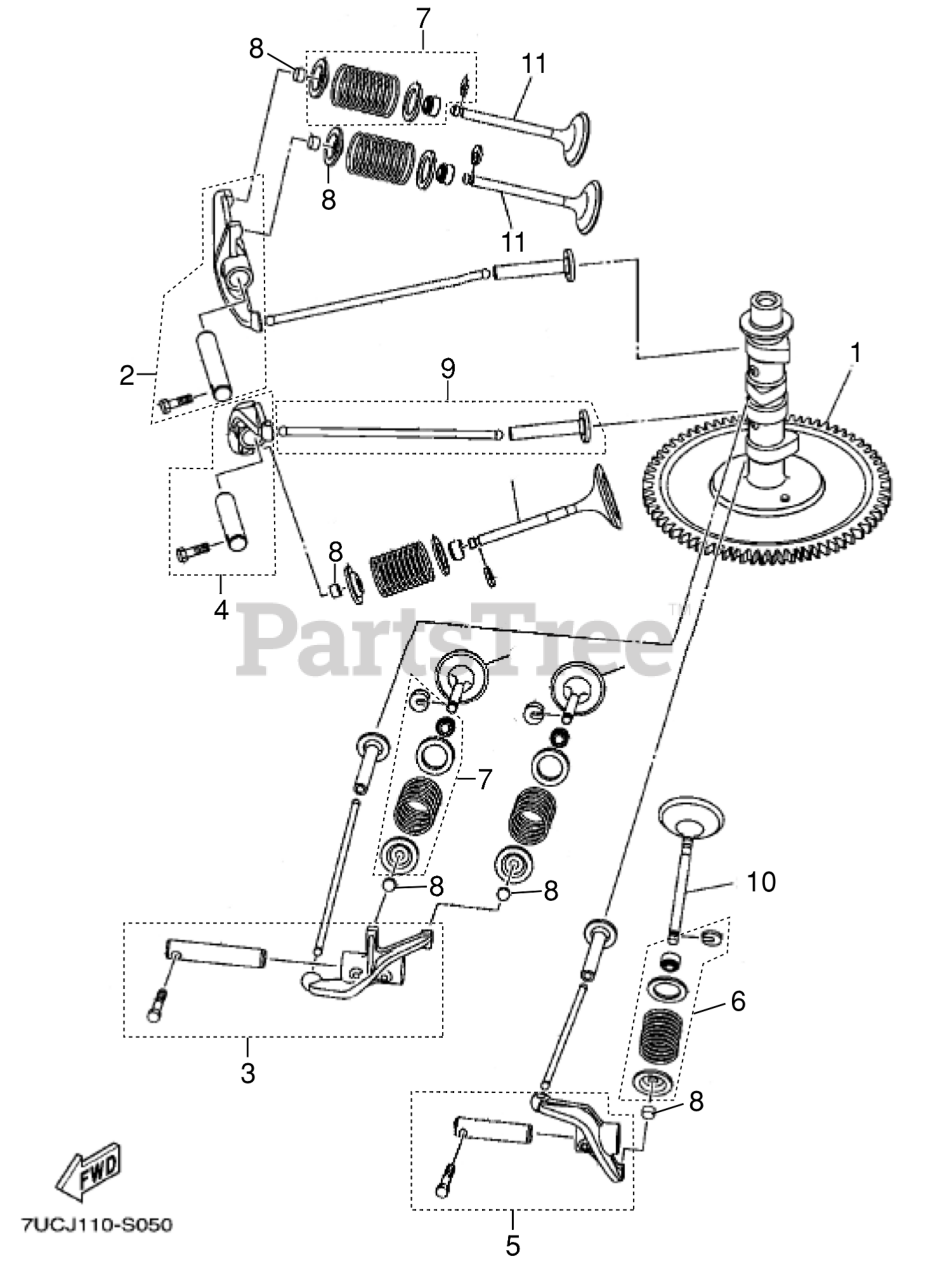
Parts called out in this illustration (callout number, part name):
1	CAMSHAFT ASSY 1 YAMAHA PN: 7UC
2	ROCKER LEVER CAMSHAFT & VALVE
3	ROCKER LEVER CAMSHAFT & VALVE
4	ROCKER LEVER CAMSHAFT & VALVE
5	ROCKER LEVER CAMSHAFT & VALVE
6	VALVE SEAT EXHAUST SPRING, SEA
7	VALVE SEAT INTAKE SPRING, SEAT
8	PAD ADJUSTING PAD X10 SERVICE
9	VALVE KIT VALVE LIFTER & ROD K
10	VALVE EXHAUST YAMAHA PN: 7UD-E
11	VALVE INTAKE YAMAHA PN: 7UD-E2
